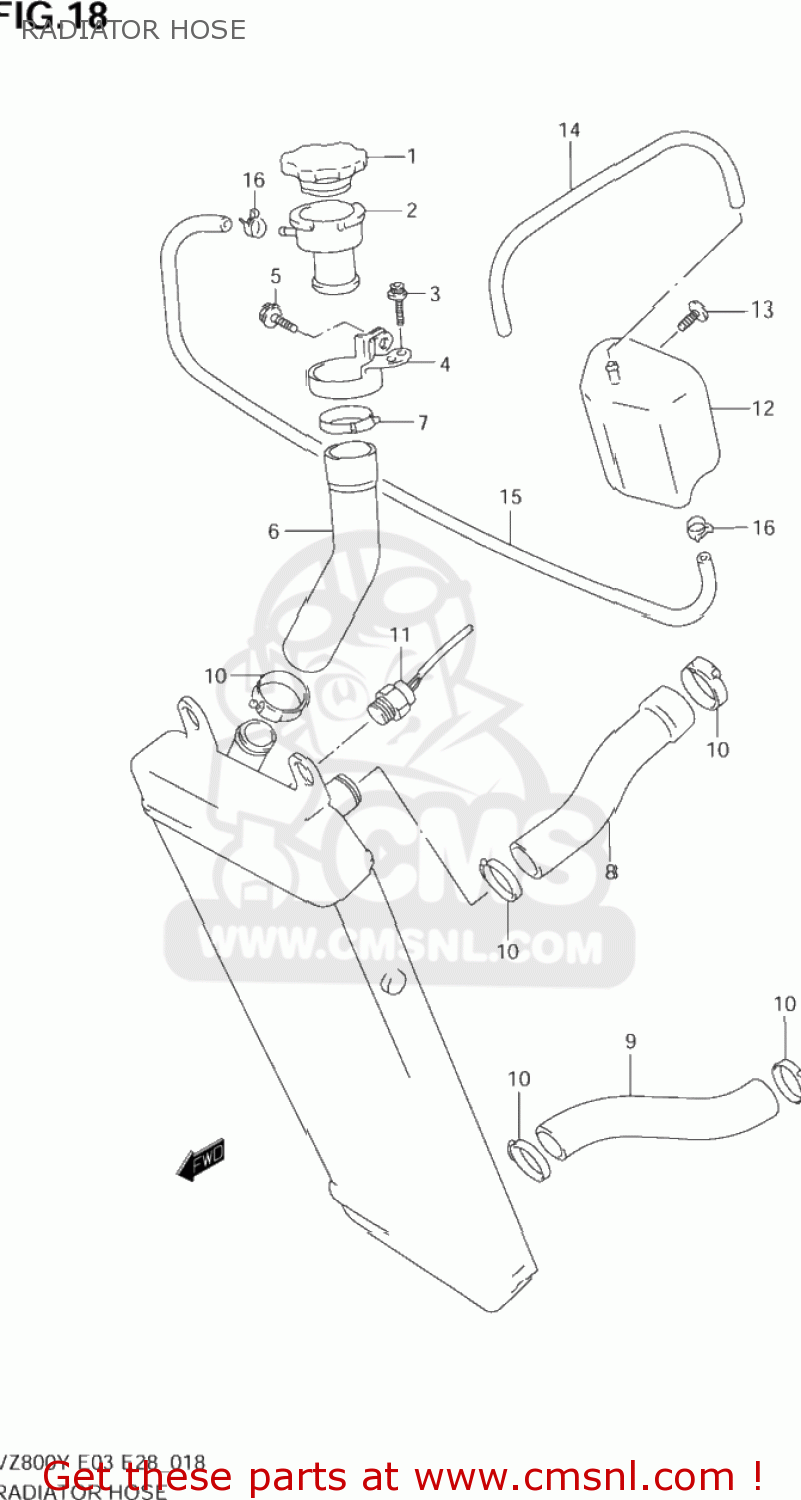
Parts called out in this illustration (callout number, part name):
1	CAP,RADIATOR
2	CONDUCTION,RADIATOR
3	BOLT MAGNETO S
4	BRACKET,CONDUCTION
5	BOLT
6	HOSE,CONDUCTION
7	CLAMP
8	HOSE,RADIATOR INLET
9	HOSE,RADIATOR OUTLET
10	CLAMP
11	SWITCH,RADIATOR FAN
12	TANK,RESERVOIR
13	SCREW 6X12
14	HOSE,RESERVOIR TANK OUTLET
15	HOSE,RESERVOIR TANK INLET
16	CLIP
